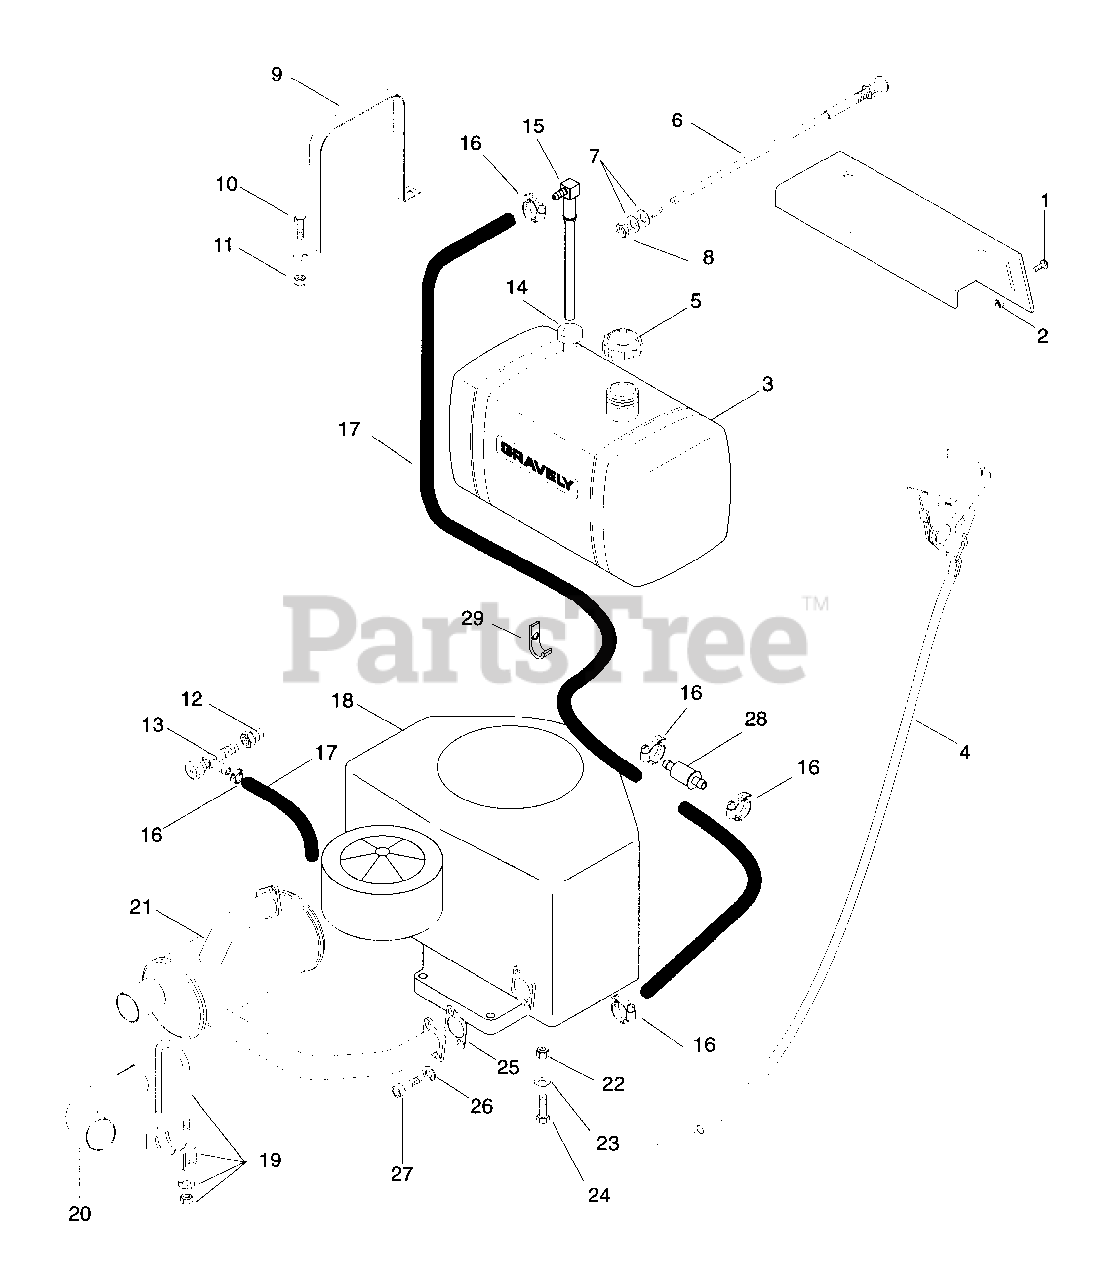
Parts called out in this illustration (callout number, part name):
1	Screw-Machine 10-32 x .50
2	Nut-Locking 10-32 Hex w/Insert
3	Tank, Fuel, Gravely PRO
4	Throttle Control Cable Assembly
5	Cap, Fuel Tank
6	Control, Choke
7	Washer-Flat-Steel .406 x .812 x .065
8	Nut, Jam .375-24
9	Strap, Fuel Tank
10	Bolt-Hex .25-20 x .63
11	Nut-Locking-Nylon .250-20 w/Insert Grade 2
12	Adapter, Oil Drain
13	Cock, Oil Drain
14	Bushing
15	Fitting, Tank
16	Hose Clamp
17	Gas Line, Bulk
18	Engine, 18 HP Magnum
19	Rivet-Pop .125 x .243
20	Deflector
21	Muffler
22	Nut-Locking-Nylon .312-18 w/Insert Grade 2
23	Washer-Flat-Steel .344 x .688 x .065
24	Bolt-Hex .31-18 x 1.50 Grade 5
25	Gasket, Exhaust
26	Washer-Lock .313 x .078
27	Screw-Cap .31-18 x .75
28	Filter, Fuel
29	J-Clamp
